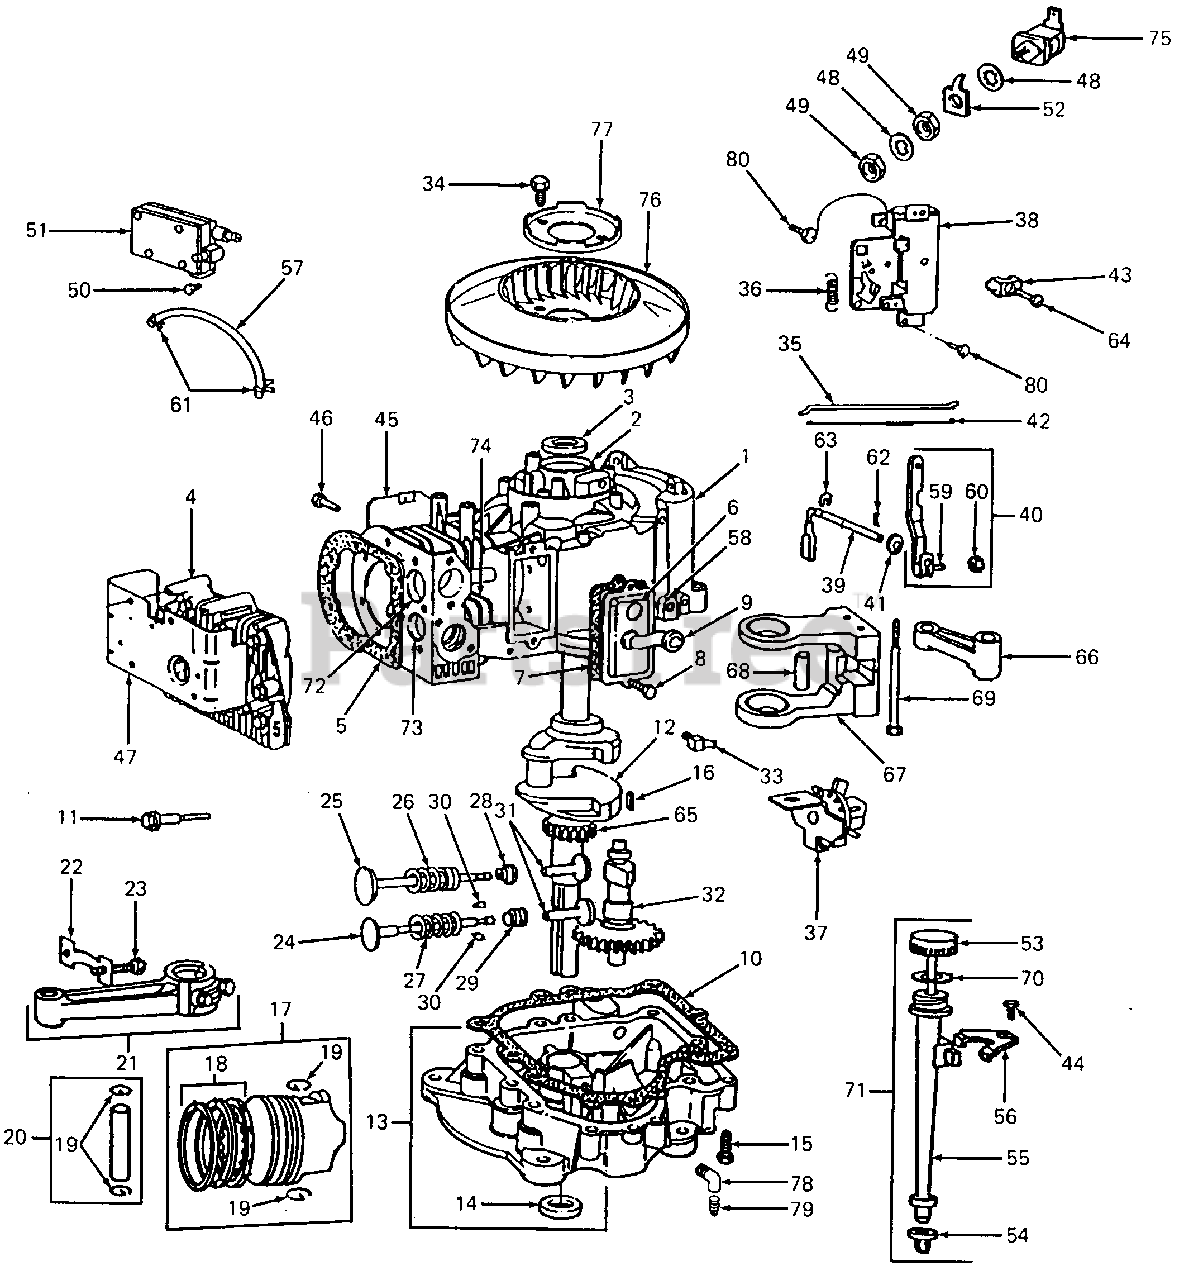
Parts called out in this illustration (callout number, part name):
1	Cylinder Assy
2	Bearing, Cylinder
3	Seal, Oil
4	Head, Cylinder
5	Gasket, Cylinder Head
6	Breather Assy
7	Gasket, Valve Cover
8	Screw, Sem
9	Tube, Breather
10	Gasket, Crankcase Cover 1/64 in. thick
11	Screw, Cylinder Head
12	Crankshaft
13	Base, Engine
14	Seal, Oil
15	Screw, Base Mounting Sem
16	Key, Flywheel
17	Piston Assy, Std
18	Piston Ring Set, Std
19	Lock, Piston Pin
20	Pin Assembly, Piston, Std
21	Rod Assy, Connecting
22	Lock, Connecting Rod Screw
23	Screw, Connecting Rod
24	Valve, Exhaust
25	Valve, Intake
26	Spring, Intake Valve
27	Spring, Exhaust Valve
28	Retainer, Intake Valve
29	Rotocoil, Exhaust Valve
30	Retainer, Exhaust Valve Rotocoil
31	Tappet, Valve
33	Connector, Fuel Pipe
34	Screw Sem
35	Link, Governor
36	Spring, Governor
37	Oil Slinger, Governor Gear & Bracket Assy
38	Plate, Governor Control
39	Crank, Governor 1/4 in. dia
40	Lever Assy, Governor for 1/4 in. dia. Crank
41	Washer, Governor
42	Spring, Governor Link
43	Clamp, Casing
44	Screw, Clamp Mounting
45	Shield, Cylinder
46	Screw, Cylinder Shield Mtg Sem
47	Cover, Cylinder Head
48	Washer, Lock, Shakeproof
50	Screw Sem
51	Pump, Impulse
52	Terminal, Spade
53	Cap & Dipstick, Oil Filler
54	Seal, Filler Tube
55	Tube, Oil Filler
56	Clamp, Oil Filler Tube
57	Line, Fuel
58	Bushing, Governor Crank 1/4 in. I.D.
59	Bolt, Governor Lever
60	Nut, Hex 10-24
61	Clamp, Fuel Pipe
62	Cotter, Hair Pin
63	Retainer, E-Ring
64	Screw Sem
65	Gear, Timing
66	Link, Counterweight
67	Counterweight Assy
68	Pin, Counterweight
69	Screw, Counterweight
70	Seal, Oil Filler Cap
71	Fill Group, Oil
72	Seat, Intake Valve Std
73	Seat, Exhaust Valve Std
74	Guide, Exhaust Valve
75	Insulator Assy
76	Fan, Flywheel
77	Retainer, Fan
78	Tube, Oil Drain
79	Plug, 1/4-18 ZNP H/Hd Auto Pipe Oil Drain
80	Screw, Carburetor
